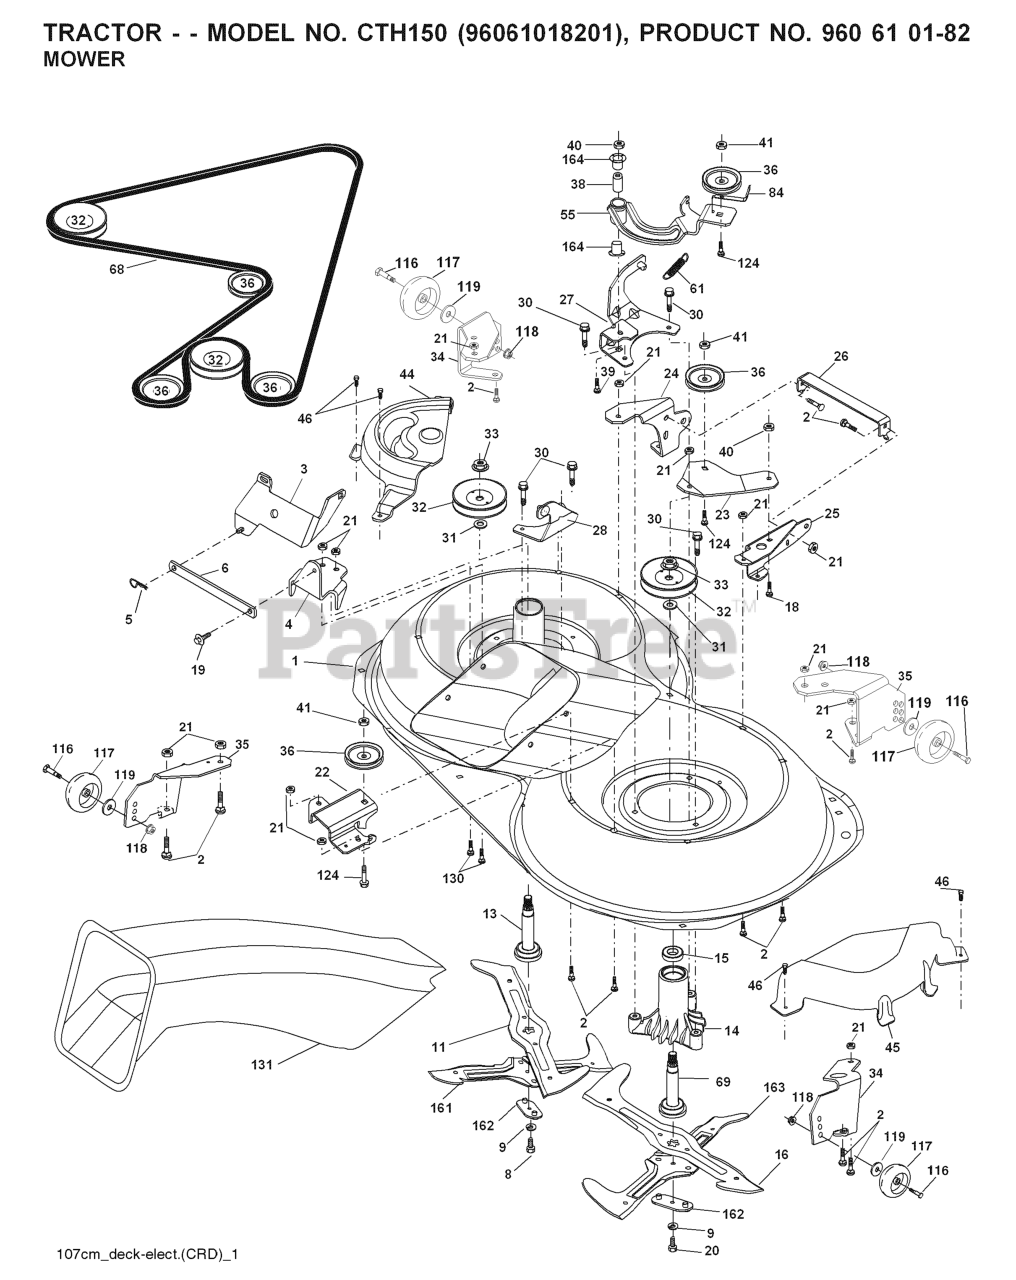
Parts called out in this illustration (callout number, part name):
1	Housing Asm. Mower 107 CRD
2	RP BOLT 5/16-18 X3/4 ZN/YEL GR
5	RETAINER-SPRNG RB
6	BAR.SWAY.92.CRD
8	BOLT.3/8-24X1.25 GR8
9	LOCKWASHER
11	BLADE.3N1.LH.CRD
13	SHAFT ASM VENT
14	HOUSING.MANDREL.VENTED (MACHD)
16	BLADE.3N1.RH.CRD
19	BOLT SHD 5/16-18
20	BOLT.3/8-24X1.25GR8. LHTHRD
21	LOCKNUT
22	BRACKET.IDLER.RR.107.CRD
25	BRACKET RF
26	SUPPORT
28	BRACKET
30	SCREW, WASHER HEAD
31	WASHER.SPACER.MANDREL
33	NUT.FLANGE.LOCK.TOP
34	BRACKET
35	BRACKET
36	PULLEY.IDLER.4.25
41	NUT LOCK FLG 3/8-16 UNC
45	COVER.MANDREL.RH.CRD
46	SCREW.1/4-20X5/8
55	ARM.IDLER.107.CRD
68	HEX-BELT 107 MOWER
69	SHAFT.ASM.W/LWR.BRG.RH.THREAD
84	KEEPER, BELT IDLER
116	BOLT.SHOULDER.3/8-16X3-5/8.
117	RP WHEEL. GUAGE RALLY
118	NUT LOCK FLG 3/8-16 UNC
119	WASHER
124	BOLT.3/8-16X1.50
130	BOLT.CARR.SQNK.5/16-18UNC.X3/4
131	CHUTE BAGGER
163	BLADE.CROSS.RH.CRD.107
164	BRNG T
